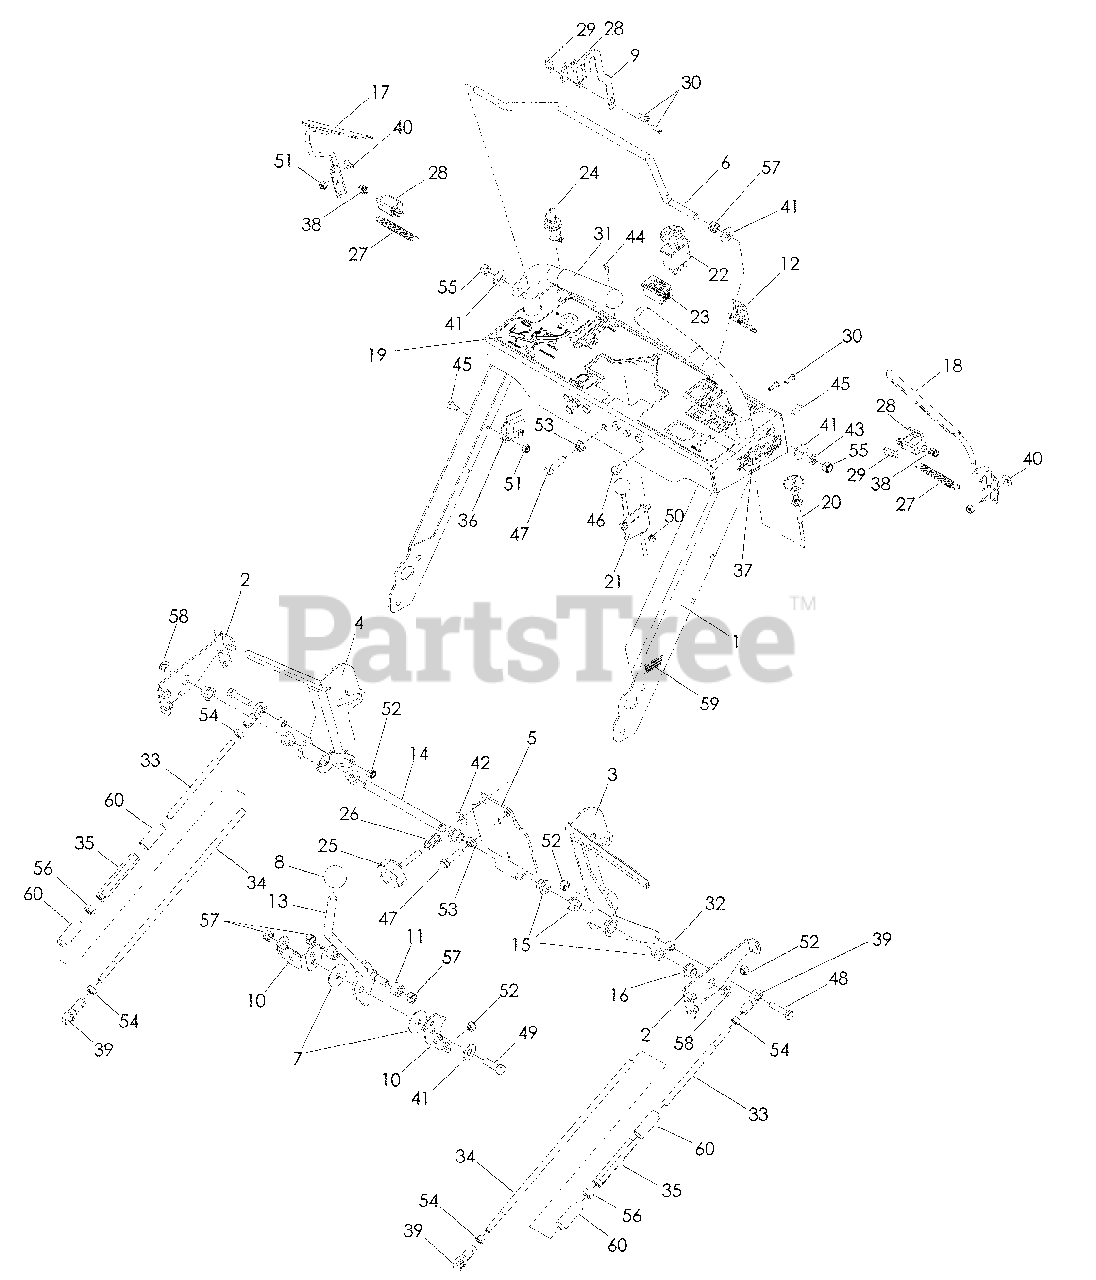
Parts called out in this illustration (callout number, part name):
1	HANDLE W/DECALS
3	DRIVE LEVER, LEFT
4	DRIVE LEVER, RIGHT
5	PLATE, TRACKING
7	WASHER, FRICTION
8	KNOB, SHIFT
9	ARM, NEUTRAL
10	PLATE, FRICTION
12	DECAL, CROWN
13	LEVER, GROUND SPEED
14	SHAFT, CROSS
15	BUSHING, FLANGED
16	BUSHING, FLANGE
17	OPERATOR, RIGHT
18	OPERATOR, LEFT
19	DECAL, CONSOLE, ETS
20	CABLE, CHOKE
21	CABLE, THROTTLE
22	SWITCH, CLUTCH
24	SWITCH W/KEY
25	KNOB, ADJUSTMENT
29	PLATE, TAPPED
30	SCREW, #10-24 x 5/8 MACH
32	SPACER, PULLEY
33	LINKAGE, SHORT
34	LINKAGE, LOWER
35	TURNBUCKLE, 3/8
37	DECAL, ETS
38	SPRING, SWITCH
39	BALL END, RIGHT
40	WASHER, ¼
41	WASHER, 3/8 FLAT STD
42	WASHER, 5/16 STD FLT
43	LOCKWASHER, 3/8
44	HCS, #10-24 x ½
45	HCS, ¼-20 x 5/8
46	HCS, 5/16-18 x ¾
47	HCS, 5/16-18 x 1¼
48	HCS, 5/16-18 x 1½
49	HCS, 3/8-16 x 1¼
50	NUT, #10-24, NYLOC
51	NUT, ¼C, NYLOC
52	NUT 5/16-18 HEX NYLOC
53	NUT, 5/16C
54	NUT, 5/16F
55	NUT 3/8-16 HEX NYLOC
57	NUT, 3/8-16 HEX CNTRLK
58	E-RING, ½"
59	DECAL, DUAL HEIGHT
